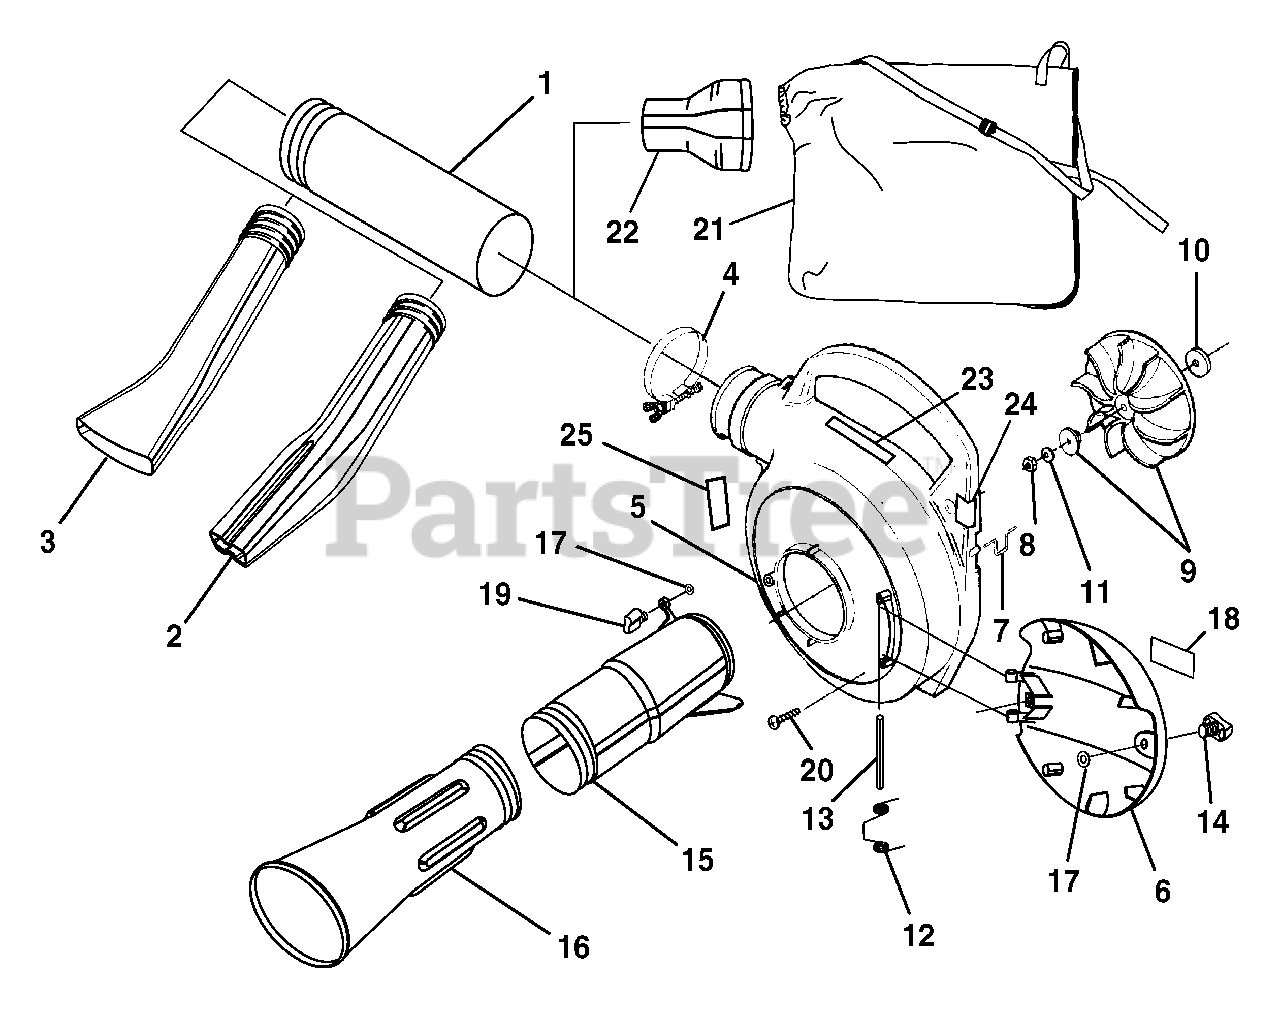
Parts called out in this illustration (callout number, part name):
1	UPPER TUBE
2	SWEEPER NOZZLE
3	LOWER NOZZLE
4	CLAMP WITH FASTENERS
5	OUTER VOLUTE HOUSING
7	WIRE LOOP
8	HEX NUT (3/8-24)
9	BLOWER FAN KIT
10	FLAT WASHER
11	BELLVILLE WASHER (3/8)
12	DOOR HINGE SPRING
13	DOOR HINGE SHAFT
14	BLOWER KNOB
15	UPPER VACUUM TUBE
16	LOWER VACUUM TUBE
18	DOOR VAC ATTACK DECAL
19	BLOWER KNOB
20	SCREW (10 x 1/2 in. TORX TRUSS HD.)
21	LEAF BAG
22	VACUUM BAG TUBE
23	WARNING DECAL
24	OUTER VOLUTE DECAL
25	FAN INTAKE DECAL
